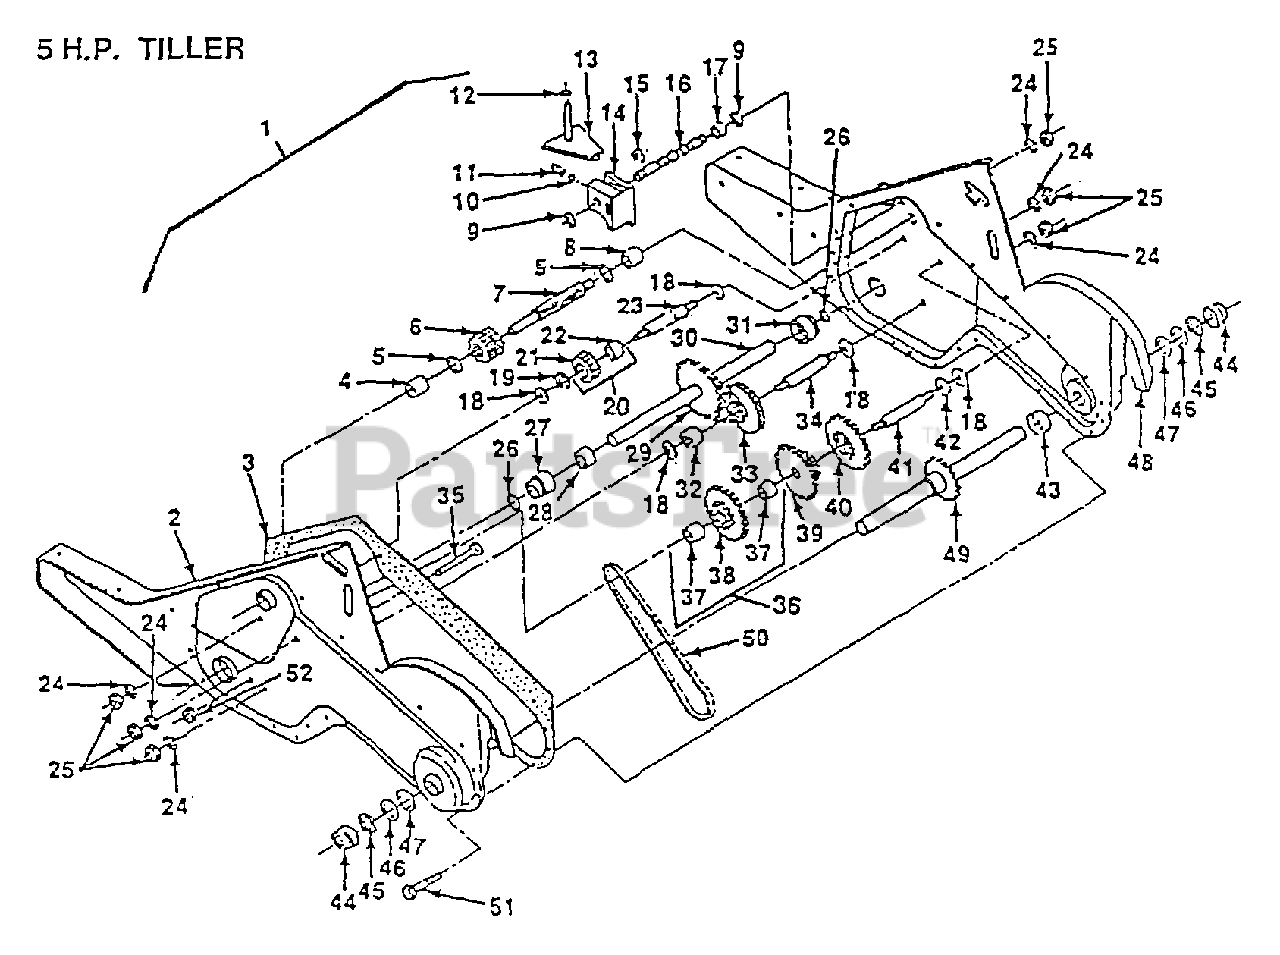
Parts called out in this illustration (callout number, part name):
3	GASKET TI
4	NEEDLE BRNG LT
5	"T, BEARING"
6	PINION-INPUT CRT
7	SHAFT-INPUT CRT
8	"TI, BEARING"
9	WASHER SEAL CRT
11	SPRING-SHIFT CRT
12	O-RING TI
13	ARM ASSY CRT
14	SHIFT FORK TI
15	KLIP RING
16	SHAFT SHIFT CRT
17	SPACER SPLIT CRT
18	WASHER
19	KLIP RING
20	GEAR ASSY CRT
21	GEAR-REV IDLR CRT
22	NEEDLE BEARING TI
23	SHAFT CRT
24	LOCKWASHER
25	NUT.ASF.HEX.7/16
26	O RING CRT
27	"CRT, BEARING"
28	BUSHING TI
29	CHAIN CRT
32	SPACER TI
33	SPRCKT 8 GEAR CRT
34	SHFT 2ND RED. CRT
35	SCRW WHIZ LOK CRT
37	BEARING
39	GEAR TI
40	GEAR TI
41	REDUCTION SHFT TI
42	BRNG RACE
43	SPACER TI
44	CUP.FORMED.
45	RING SPIRAL CRT
49	SHAFT ASSY TI
50	CHAIN.50 LINK TI
51	SCREW CRT
52	NUT.HEX.5/16-18
53	GREASE PREMIUM-1
